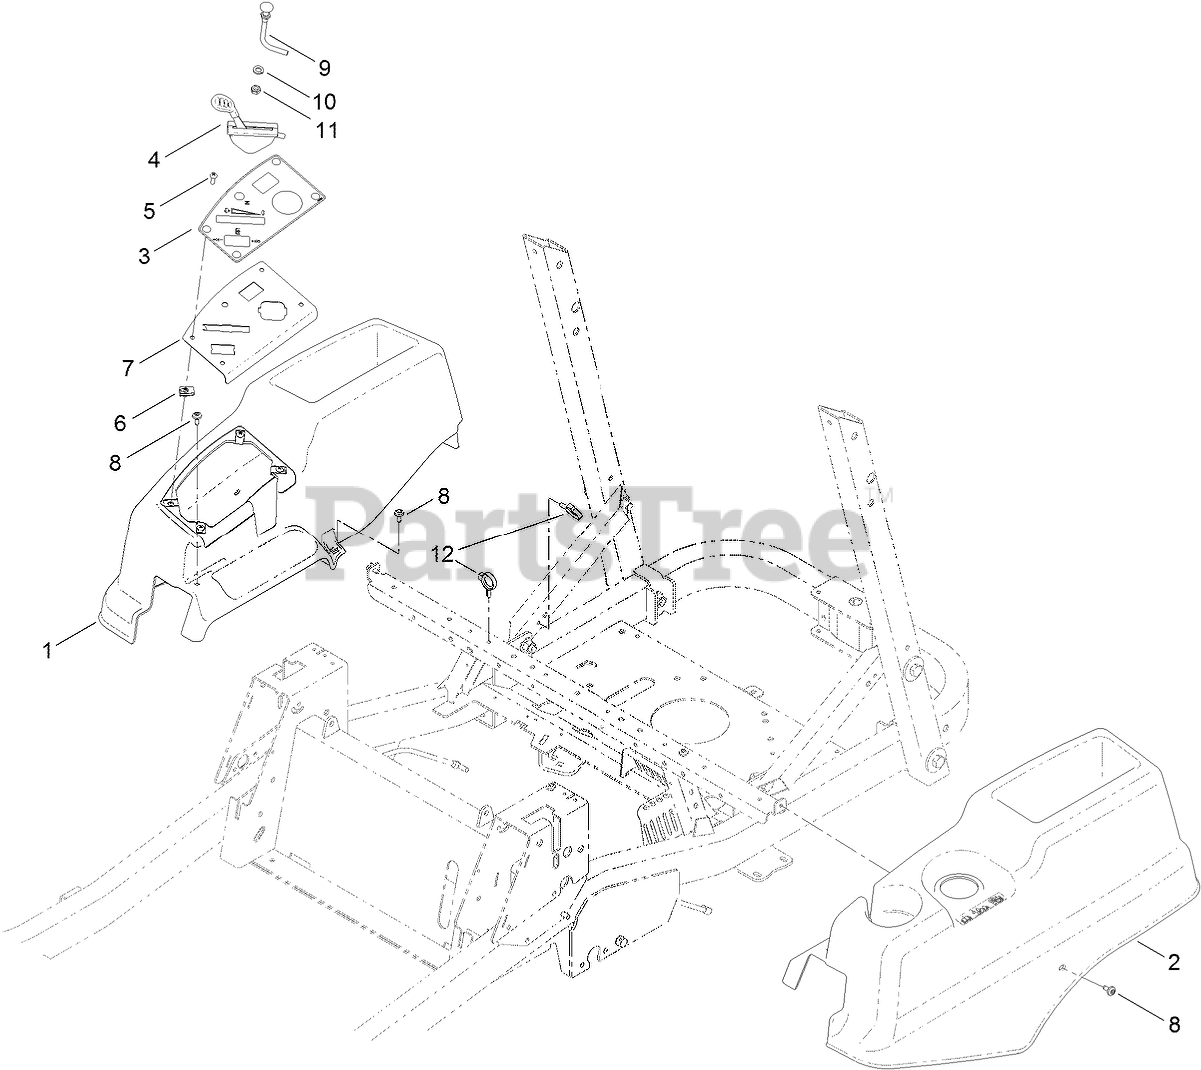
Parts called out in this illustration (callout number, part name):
1	POD-RH
2	POD-LH
3	DECAL-PANEL, CONTROL
4	CABLE-THROTTLE
5	SCREW-PRH
7	PANEL-CONTROL
8	SCREW-SHOULDER
9	CABLE-CHOKE
10	WASHER-LOCK
11	NUT-HJ
12	CLAMP-HOSE
